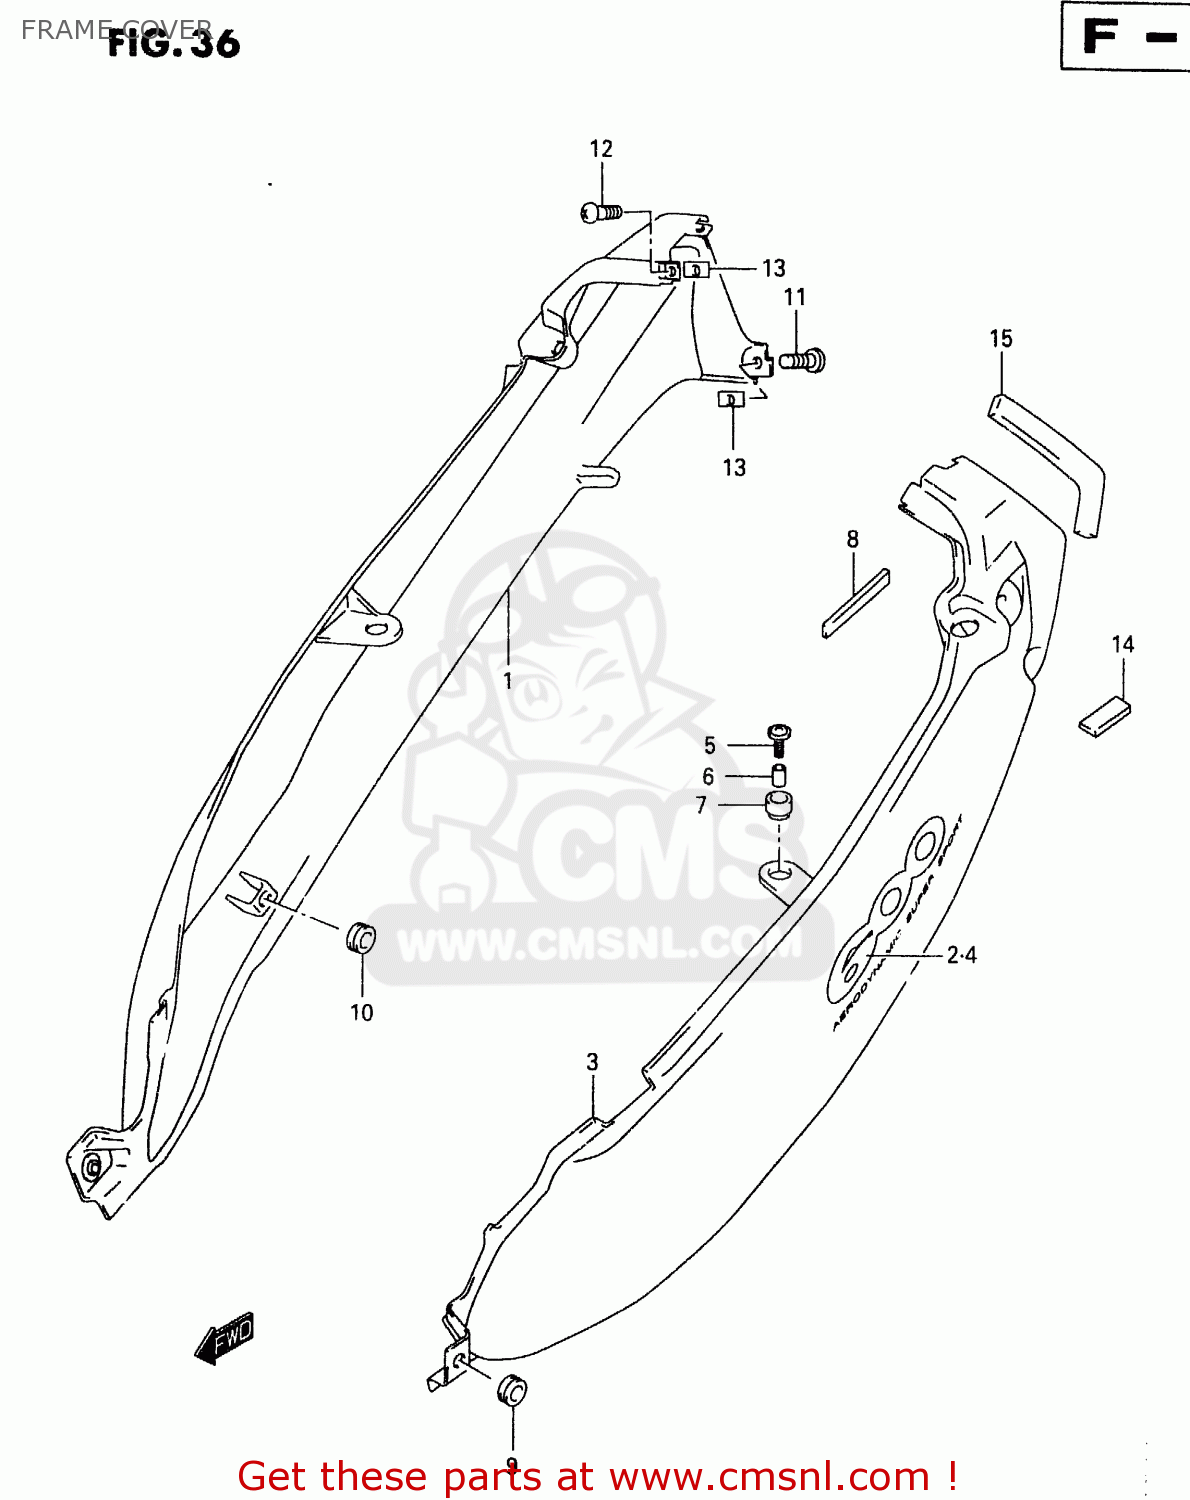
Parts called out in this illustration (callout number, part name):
1	COVER,FRAME,R(BLUE)
2	EMBLEM,FRAME COVER,R
3	COVER,FRAME,L(RED)
4	EMBLEM,FRAME COVER,L
5	SCREW(6X20)
6	SPACER(6.5X10X9.4)
7	CUSHION
8	CUSHION,UNDER COWLING NO.1
9	CUSHION
10	CUSHION
11	SCREW
12	SCREW
13	NUT
14	CUSHION
15	CUSHION,FRAME COVER
